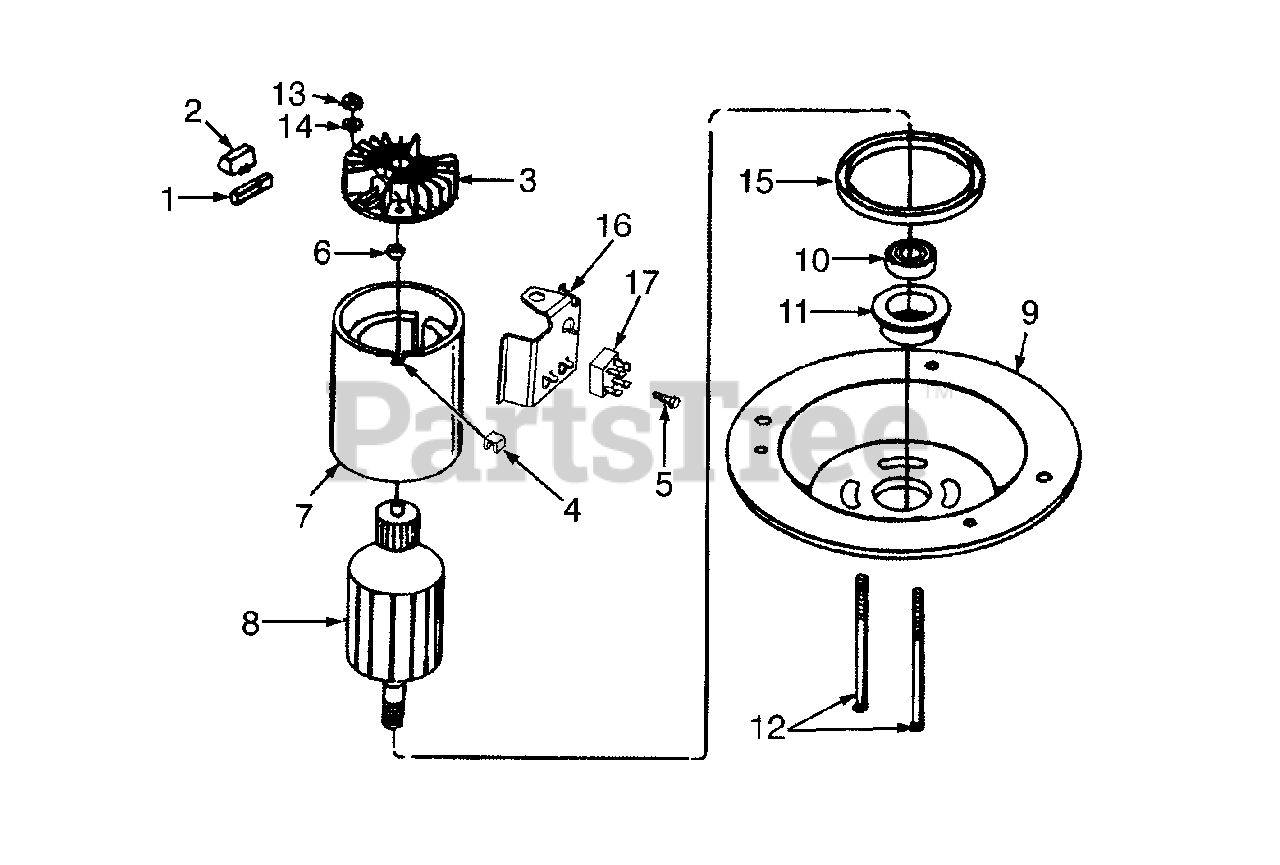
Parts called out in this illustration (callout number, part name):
1	Brush & Liner Assembly
2	Brush Holder Cap
3	End Shield Assembly. W/plug
4	Insulator Wire
5	Hex Tap Scr. #10-16 x .62" Lg.
6	Needle Bearing
7	Not A Serviceable Part
8	Armature Assembly
9	Motor End Plate Assembly
10	Ball Bearing
11	Bearing Adapter
12	Carriage Bolt
13	Hex L-Nut 1/4-20 Thd.
14	Fl. Washer .26" I.D. x .72"
16	Brkt. Rectifier/Heat Sink
17	Rectifier
